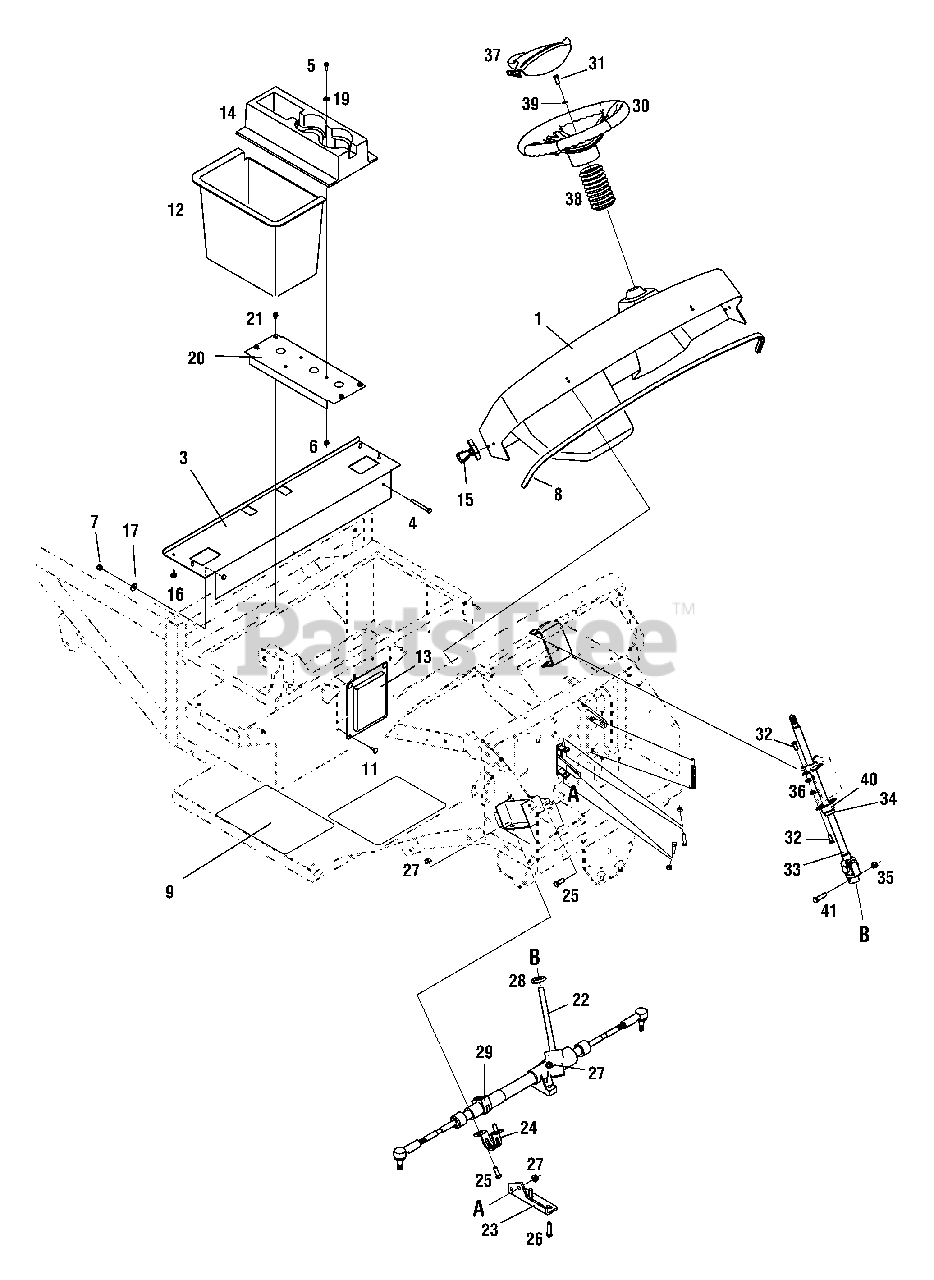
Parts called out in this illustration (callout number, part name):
2	Hood Mounting Plate
5	Hex Screw, 1/4-20 x .75, Gr5
6	Hex Lock Nut, Nylon, 1/4-20
7	Hex Lock Nut, Nylon, 5/16-18
8	Trim, Bulb Seal, 1/4
9	Foot Pad, Abrasive
10	Rivet, Pop, .187
11	Rivet, Pop, .188
12	Container, Bulkhead
13	Panel, Shift Cover
14	Console, Cup Holder
15	Handle, Latch
16	Bumper, Rubber
17	Washer, Flat, .349 x .879 x .063
18	Washer, Flat, .194 x .62 x .063
19	Washer, Flat, .39 x 1.38 x .062
22	Gear Assembly, Steering
25	Hex Screw, 3/8-16, 1.00, Gr8
26	Hex Screw, 3/8-16, 1.50, Gr5
27	Nut, Flange Lock, 3/8-16
28	Grommet, Steering Shaft
29	Bushing, Rubber
30	Wheel, Steering
31	Hex Screw, 5/16-18, .75, Gr5, Patch
32	Hex Screw, 5/16-18, .75, Gr5
33	Shaft, Steering, 5/8 Spline
34	Collar, .75
35	Nut, Hex Lock Nylon, 3/8-16
36	Nut, Flange Lock, 5/16-18
37	Cover, Steering Wheel
38	Bellow, Steering, 4.75 Lg
39	Washer, Flat, .344 x .688 x .065
40	Bearing, Flange, .75 ID, Self-Aligning
41	Hex Screw, 3/8-16, 1.75, Gr5
